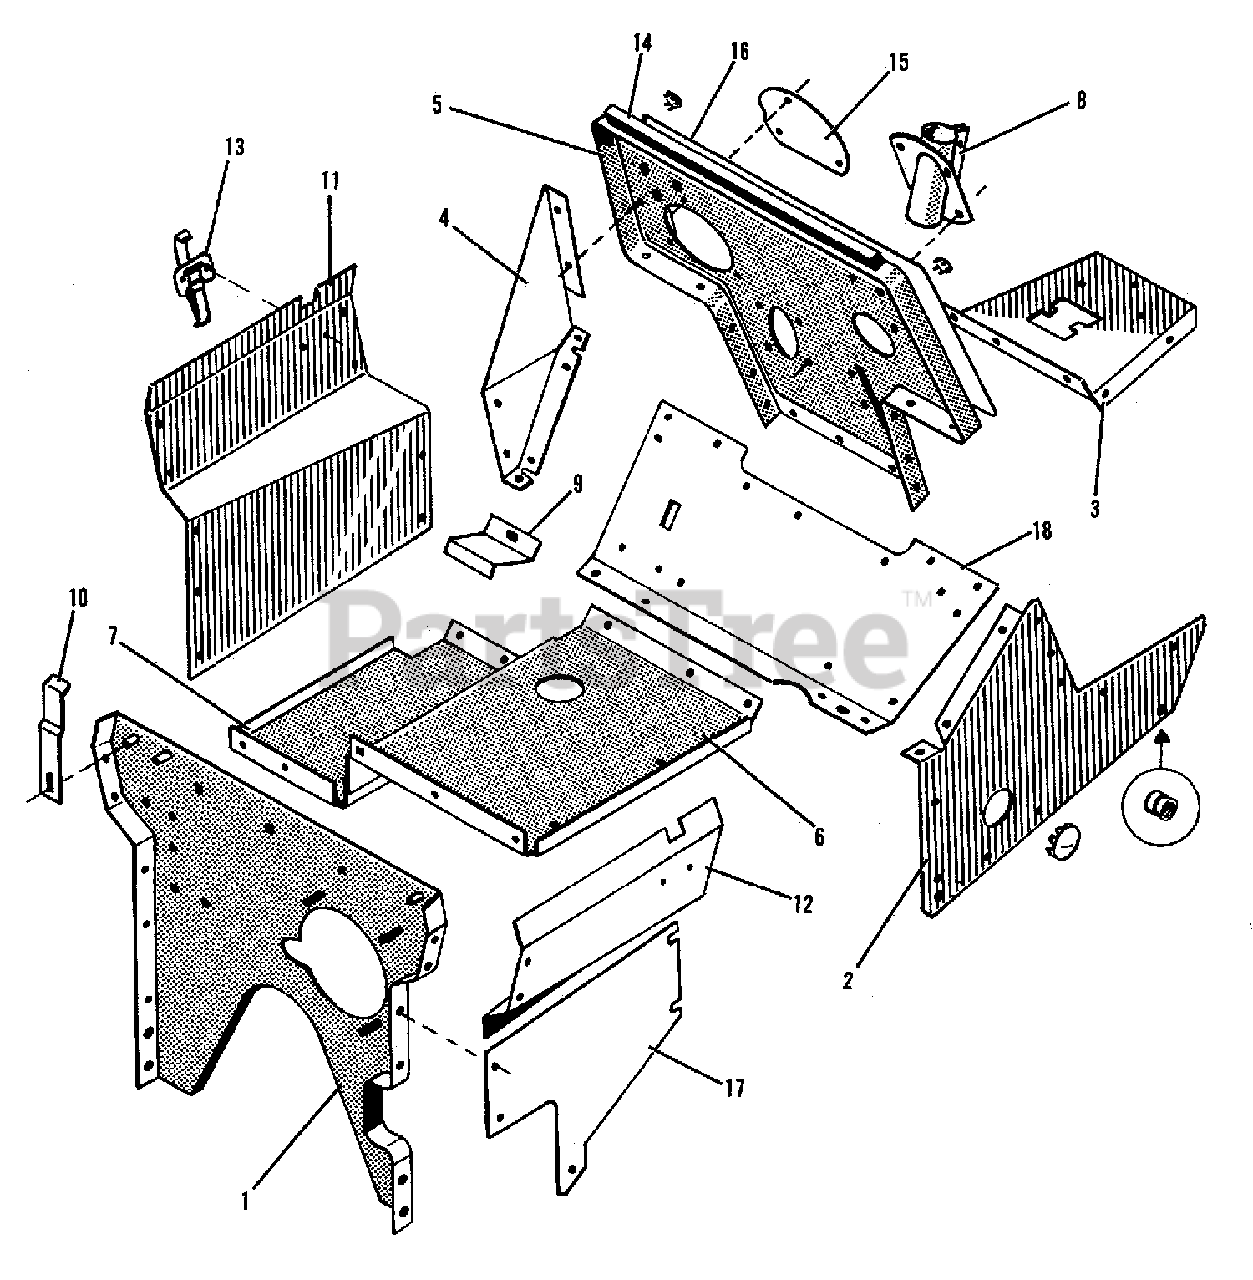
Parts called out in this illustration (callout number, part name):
1	WALL ASSEMBLY, Front Support
1	GROMMET, Rubber
1	CAPSCREW, 5/16NC x 3/4
1	LOCKWASHER, 5/16
2	SIDE SHEET, R.H.
2	SIDE SHEET, L.H.
2	CAPSCREW, 5/16NC x 3/4
2	LOCKWASHER, 5/16
2	NUT, 5/16NC
3	COVER, Control Linkage (Variable Drive Models)
3	COVER, Control Linkage (Hydrostatic Drive Models)
4	SIDE, Dashboard, R.H.
4	SIDE, Dashboard, L.H.
5	PANEL, Instrument
5	CAPSCREW, Hexagon Head, 1/4-20 NC x 1-1/4
5	LOCKWASHER, 1/4
5	NUT, Hexagon, 1/4NC
6	FLOOR, Gas Tank
6	CAPSCREW, Hexagon Head, 1/4-20 NC x 1-1/4
6	LOCKWASHER, 1/4
6	NUT, Hexagon, 1/4NC
7	FLOOR, Battery
8	CLAMP ASSEMBLY, Steering Post
8	CAPSCREW, Hexagon Head, 1/4-20 NC x 1-1/4
8	LOCKWASHER, 1/4
8	NUT, Hexagon, 1/4NC
9	STOP, Battery
9	BOLT, Round Head, 5/16NC x 5/8
9	WASHER, 5/16
9	LOCKWASHER, 5/16
9	NUT, Hexagon, 5/16NC
10	CLAMP, Battery
10	WASHER, 5/16
10	LOCKWASHER, 5/16
10	NUT, Hexagon, 5/16NC
11	PANEL, R.H. Side
11	CAPSCREW, 1/4 NC x 5/8
11	LOCKWASHER, 1/4
12	PANEL L.H. side
12	CAPSCREW, 1/4 NC x 5/8
12	LOCKWASHER, 1/4
13	LATCH, Hood
13	LOCKWASHER, #10 External Tooth
14	TAPE, Foam (14-1/2")
15	PLATE, Cover
16	DECAL, Instrument Panel (Models 310, 312 & 314)
16	DECAL, Instrument panel (Models 310-D, 312-D & 314-D)
16	DECAL, Instrument Panel (Models 312-H & 314-H)
17	PANEL, L.H. Side Bottom (Manual P.T.O.)
17	PANEL, L.H. Side Bottom (Electric P.T.O)
17	PLUG, Bottom
18	PANEL, Bottom (Instrument Panel)
